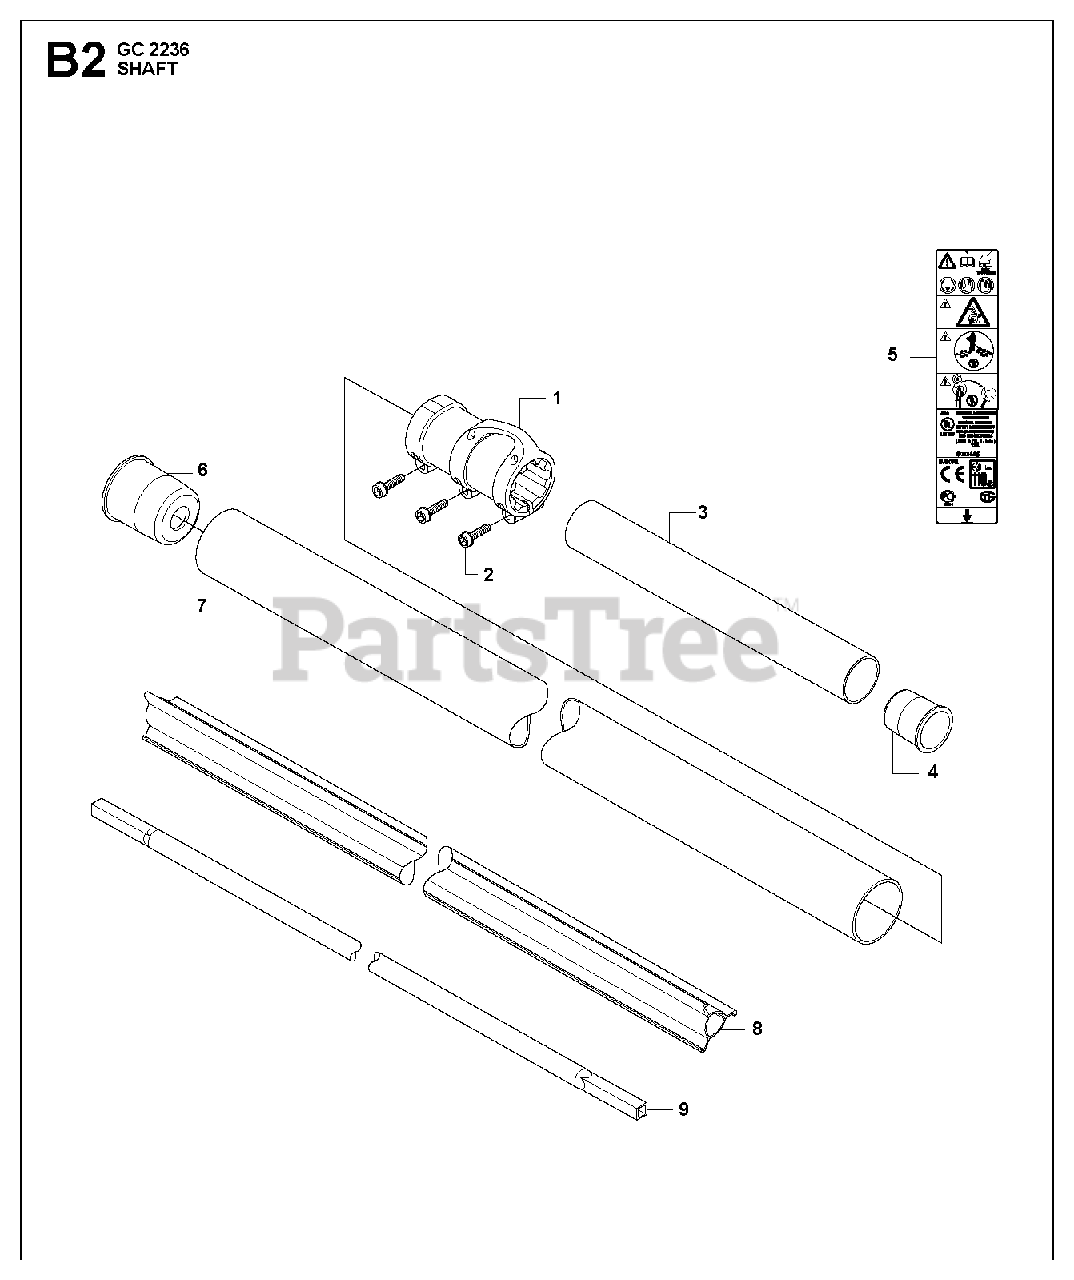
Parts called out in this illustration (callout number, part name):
3	TUBE
4	SPACER SLEEVE
7	TUBE
8	GUIDE
9	SHAFT
